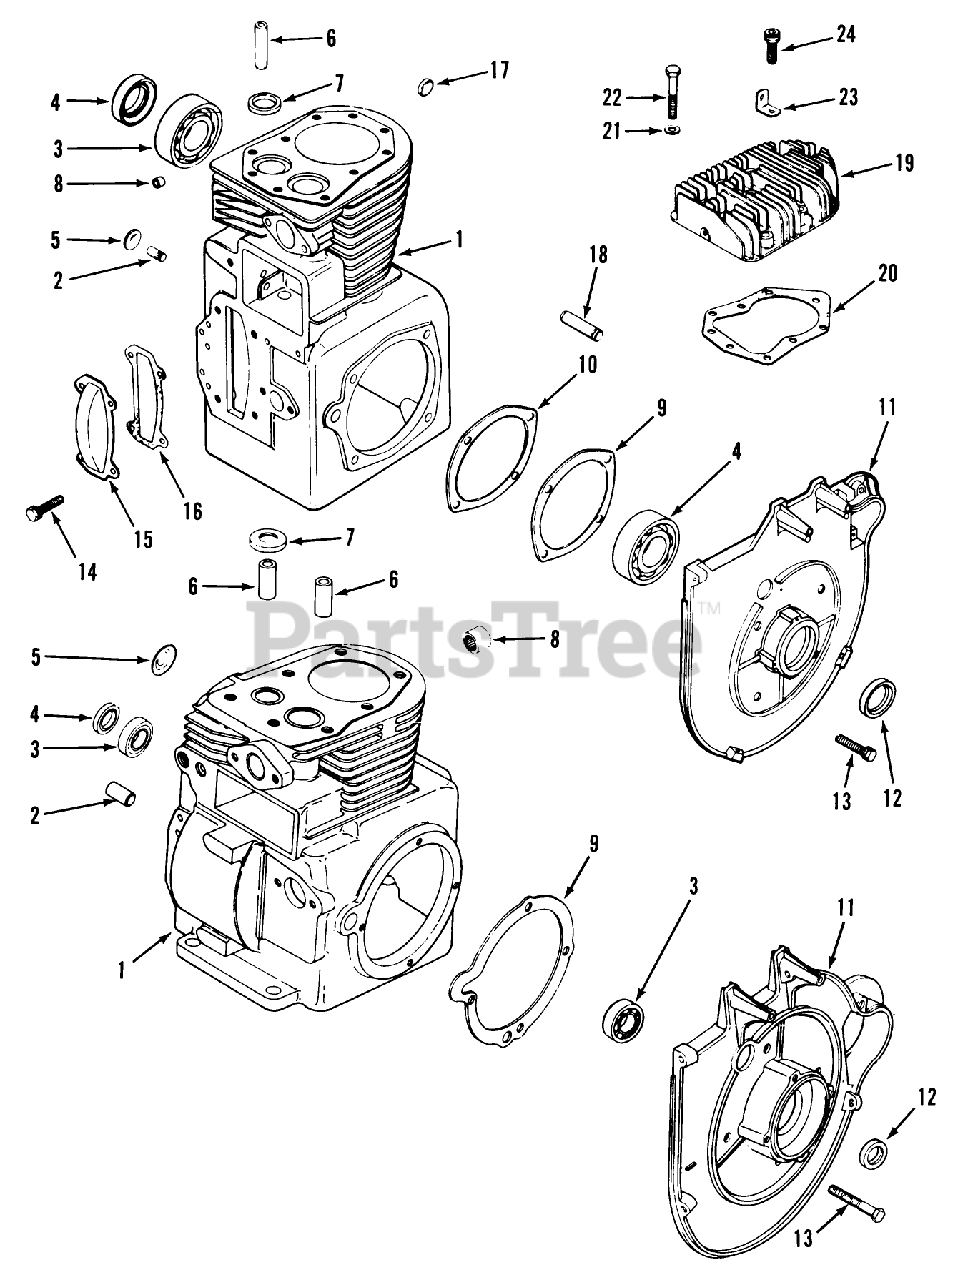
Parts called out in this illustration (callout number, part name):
1	Cylinder Block-Service With Short Block (Includes Crankshaft)
2	KOHLER 230125-5
3	KOHLER 231625
4	KOHLER X-583-2
5	KOHLER X-230-11
6	KOHLER 230007-5
7	KOHLER 230170
8	KOHLER 234866
9	KOHLER 41-041-07
10	KOHLER 47-522-05
11	KOHLER 41-009-02
12	KOHLER X-583-1
13	KOHLER X-176-1
14	KOHLER X-132-6
15	KOHLER 235026
16	KOHLER 235025
17	KOHLER X-702-12
18	KOHLER 236559
19	KOHLER 41-755-25
20	KOHLER 41-041-10
21	KOHLER 220534
22	KOHLER 41-086-02
23	KOHLER 47-455-02
24	KOHLER 47-086-17
